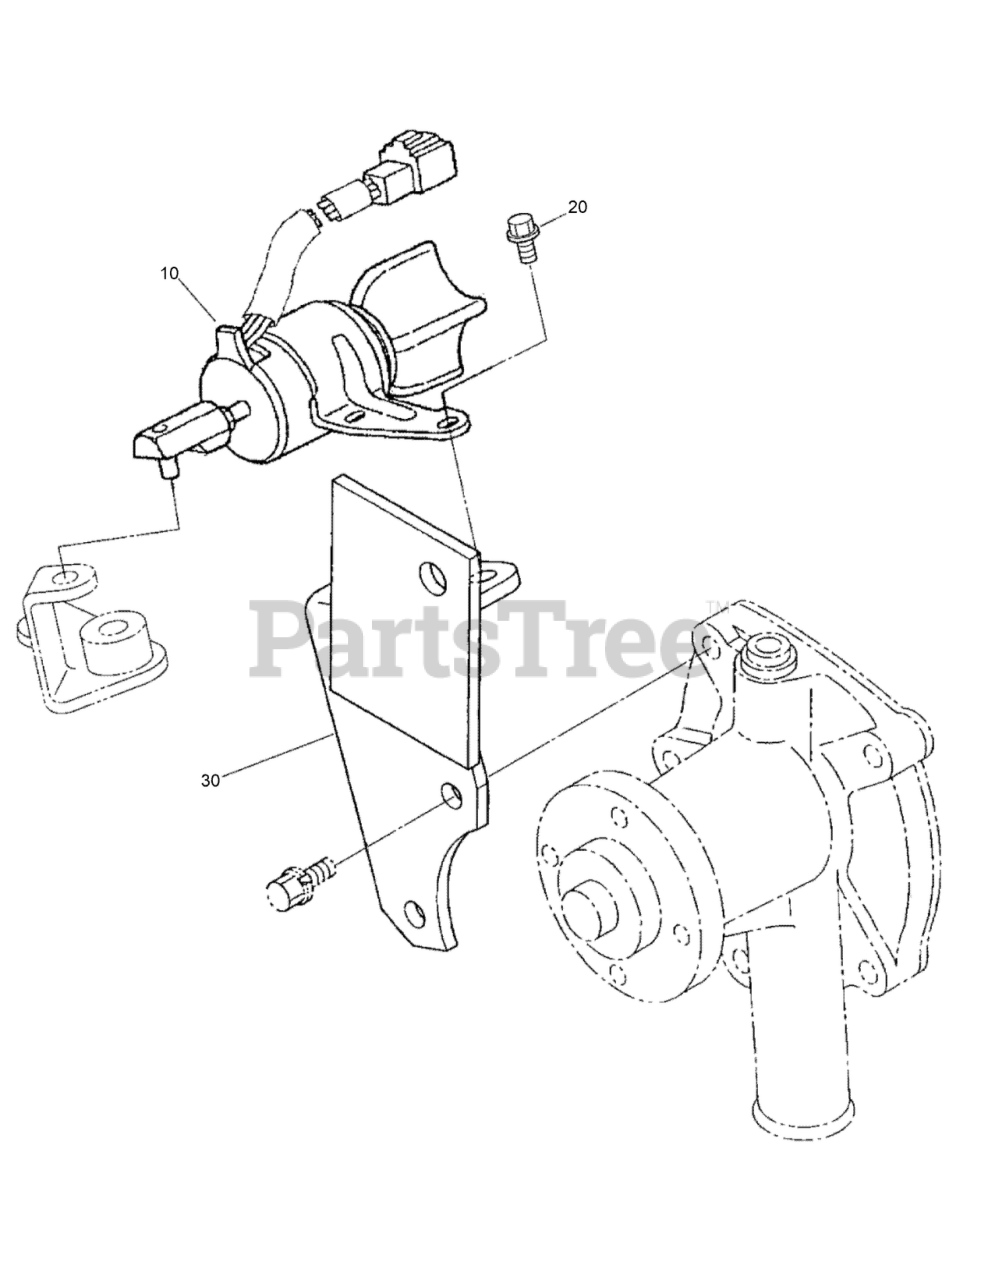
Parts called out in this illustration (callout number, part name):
10	SOLENOID,STOP
20	BOLT-FLANGE
30	COMP.SUPPORT
